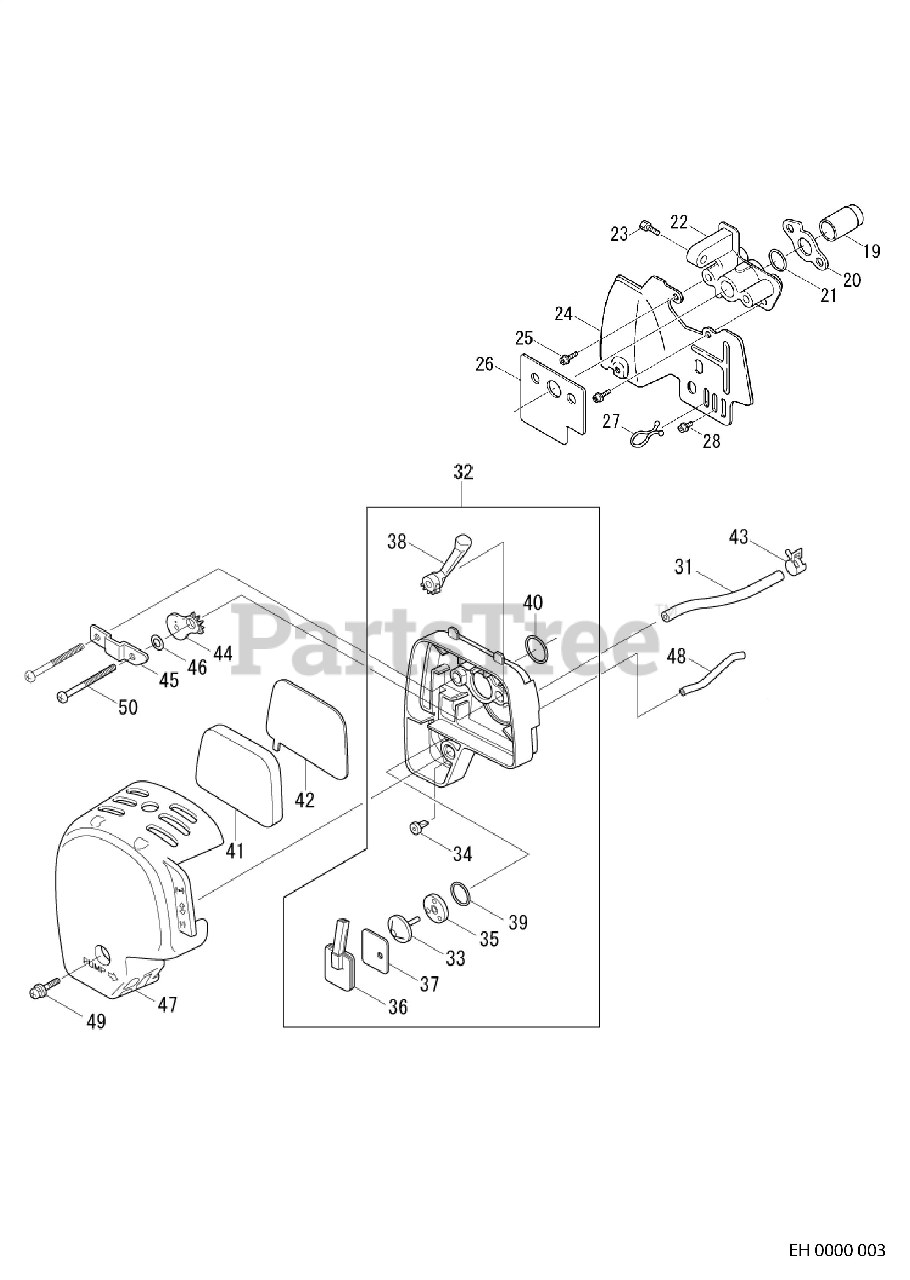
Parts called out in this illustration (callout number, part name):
20	GASKET, INSULATOR
21	O-RING
23	SCREW, ADJUST
24	INSULATOR, CARBURETOR
25	BOLT - SOCKET HEAD
26	GASKET, CARBURETOR
27	CLAMP
28	BOLT - SOCKET HEAD
31	PIPE, BREATHER
32	CLEANER PLATE ASSY
34	VALVE, CHECK - (1)
35	PLATE, CHECK VALVE
36	PLATE, SEPARATOR COMPL
37	GASKET, SEPARATOR
41	ELEMENT, AIR CLEANER
42	ELEMENT, AIR CLEANER
47	COVER, AIR CLEANER
48	PIPE
49	SCREW ASSY
50	SCREW
